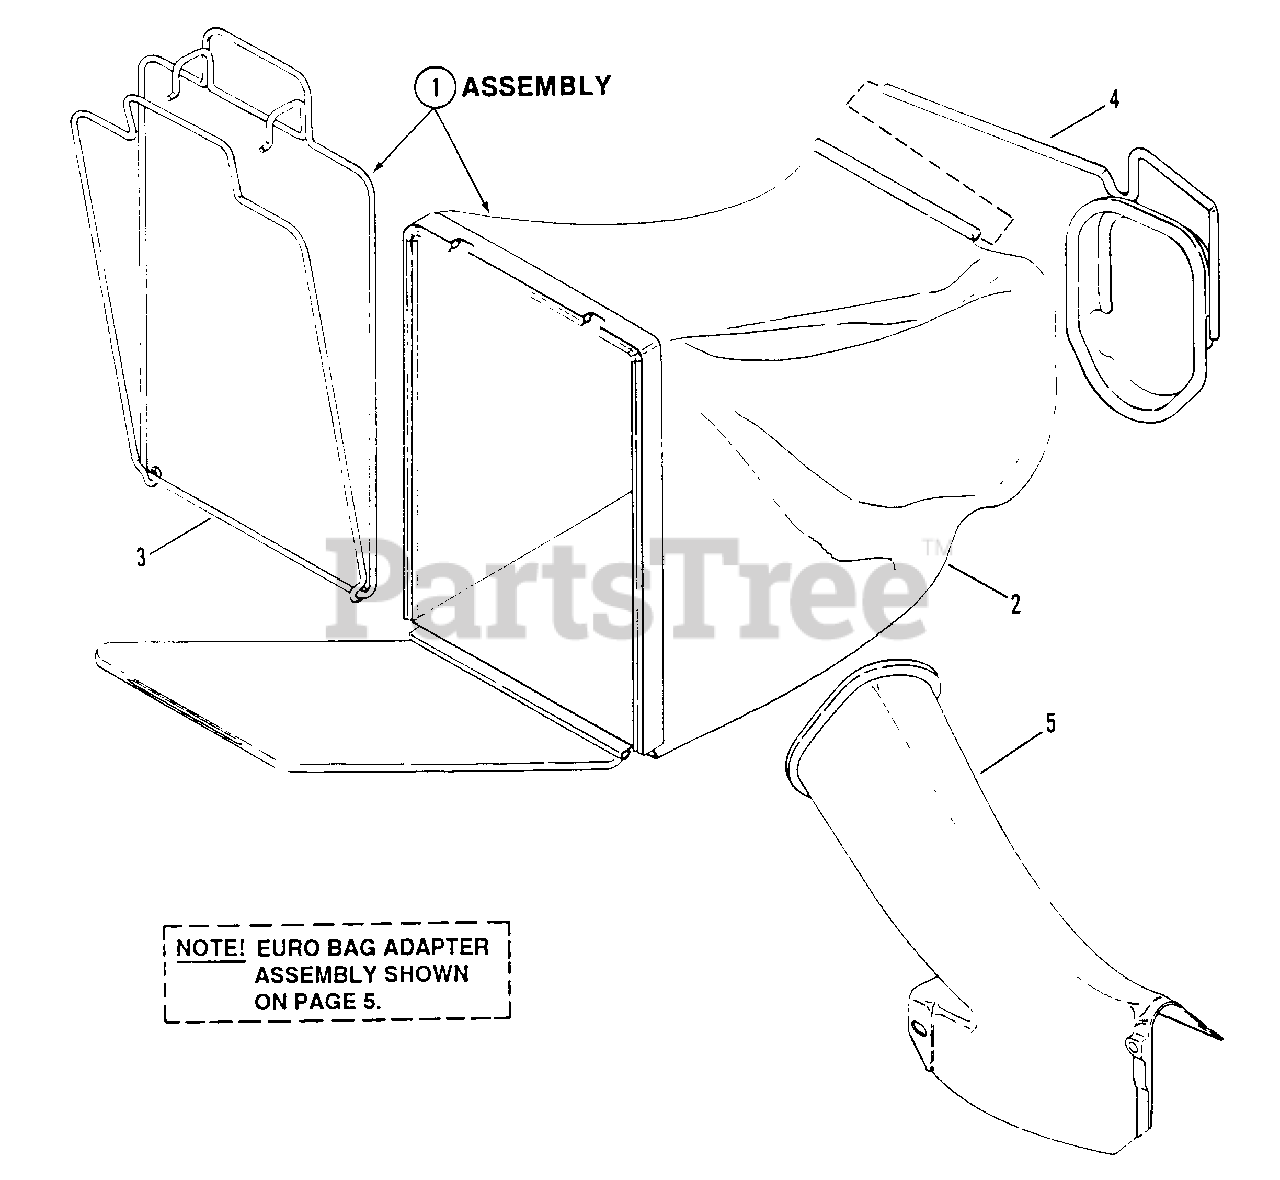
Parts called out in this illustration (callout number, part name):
1	ASSEMBLY, Grass Bag, 14" Wide
2	GRASS BAG, (14.5" Wide) (Black)
3	ASSEMBLY, Bag Wire, 14" Wide
4	CONNECTOR, Grass Bag
5	ADAPTER, Bag
